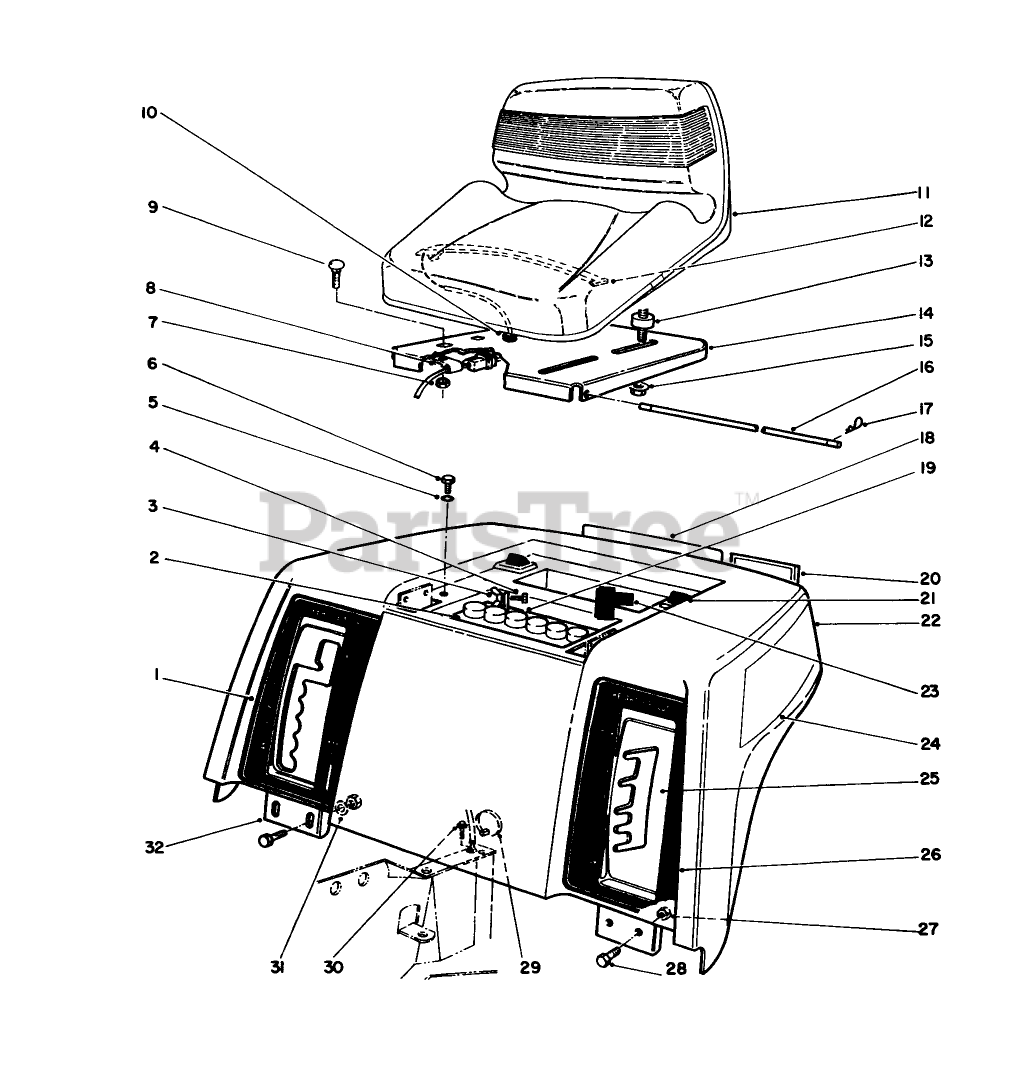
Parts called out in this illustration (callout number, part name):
2	SEE SB MISC 14
3	NUT-WING
4	SCREW-HH
6	SCREW-THD ROLL, HWH
7	NUT-KEPS
9	SCREW-CARR
10	GROMMET
12	SWITCH-SEAT
13	ISOLATER-SEAT
15	NUT-HF
16	PIVOT-SEAT
20	REFLECTOR
23	BOOT-TERMINAL
27	NUT-LOCK, NI
28	SCREW-HH
29	TIE-CABLE
30	SCREW-HWHTF
31	WASHER-PLAIN
